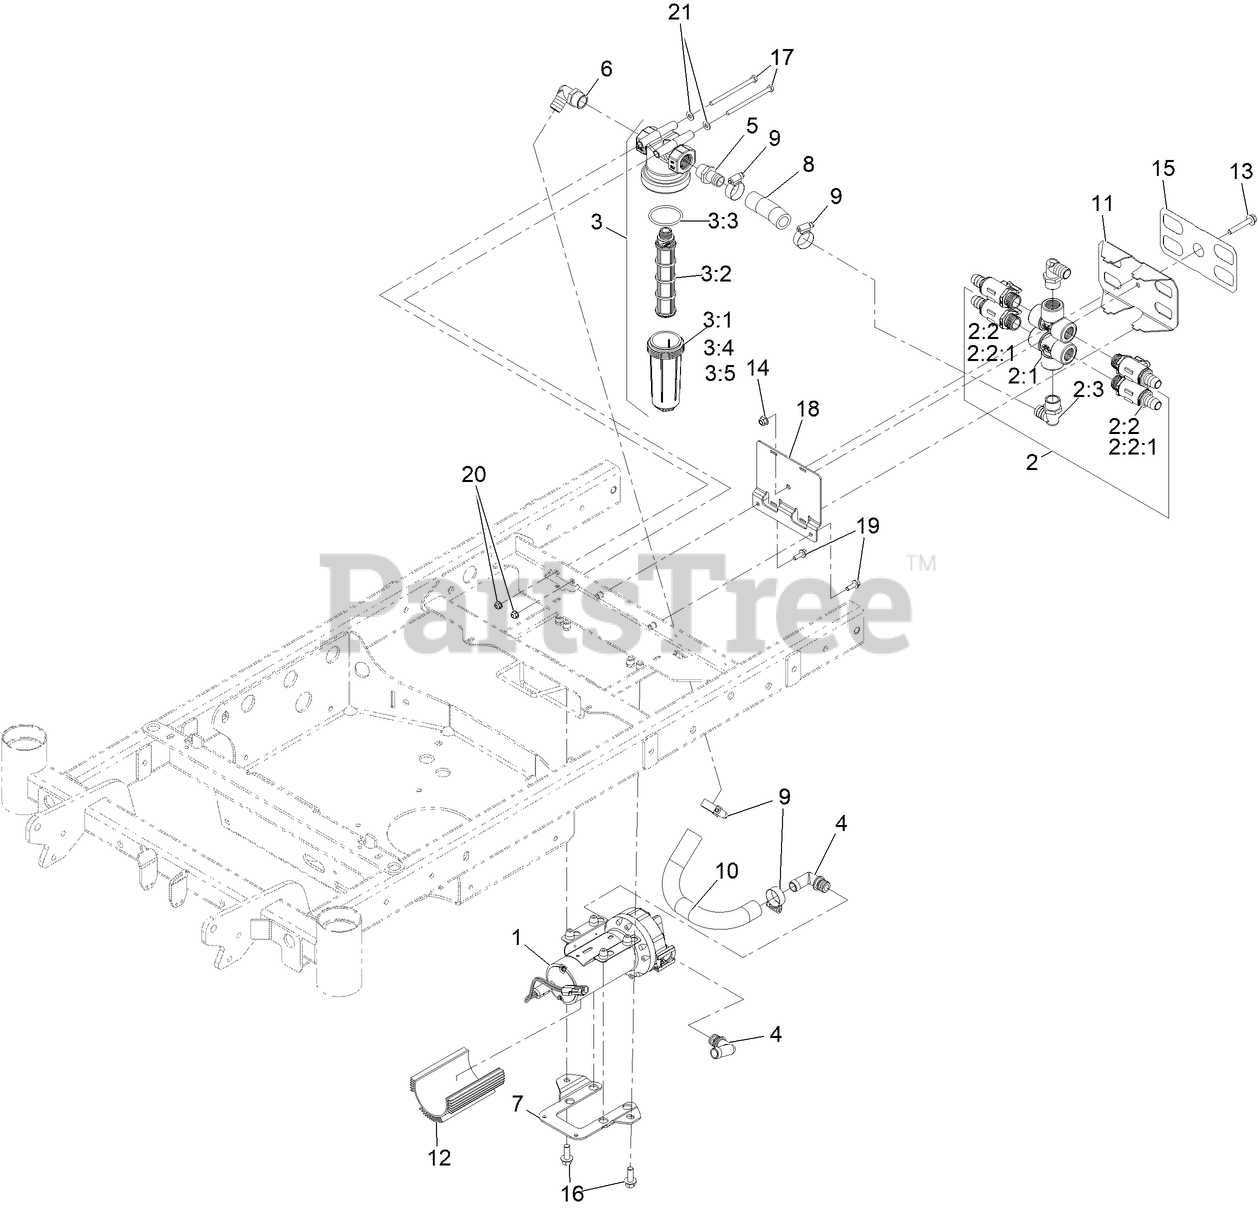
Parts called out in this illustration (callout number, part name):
1	PUMP-5.3 GPM
2	ASM-VALVE, SELECTOR
2:1	FITTING-TEE
2:2:1	O-RING, -213
2:3	FITTING-ELBOW, 90
3	STRAINER-T, 50 MESH
3:1	CUP-FILTER
3:2	SCREEN-FILTER, 50 MESH
3:3	ORING-FILTER, CUP
3:4	PLUG-FILTER
3:5	ORING-FILTER, PLUG
4	FITTING-ELBOW
5	HOSEBARB
6	FITTING-ELBOW, 90
7	BRACKET-MOUNT, PUMP
8	HOSE-SPRAY
9	CLAMP-HOSE
10	HOSE-FORMED
11	BRACKET-VALVE, SELECTOR
12	HEATSINK-3.0""
13	SCREW-HHF
14	Nut-Hex Flange
15	DECAL-VALVE
16	SCREW-HHF
17	SCREW-HHCS
18	MOUNT-VALVE
19	Screw-HHF
20	Nut-Hex Flange
21	WASHER-FLAT
